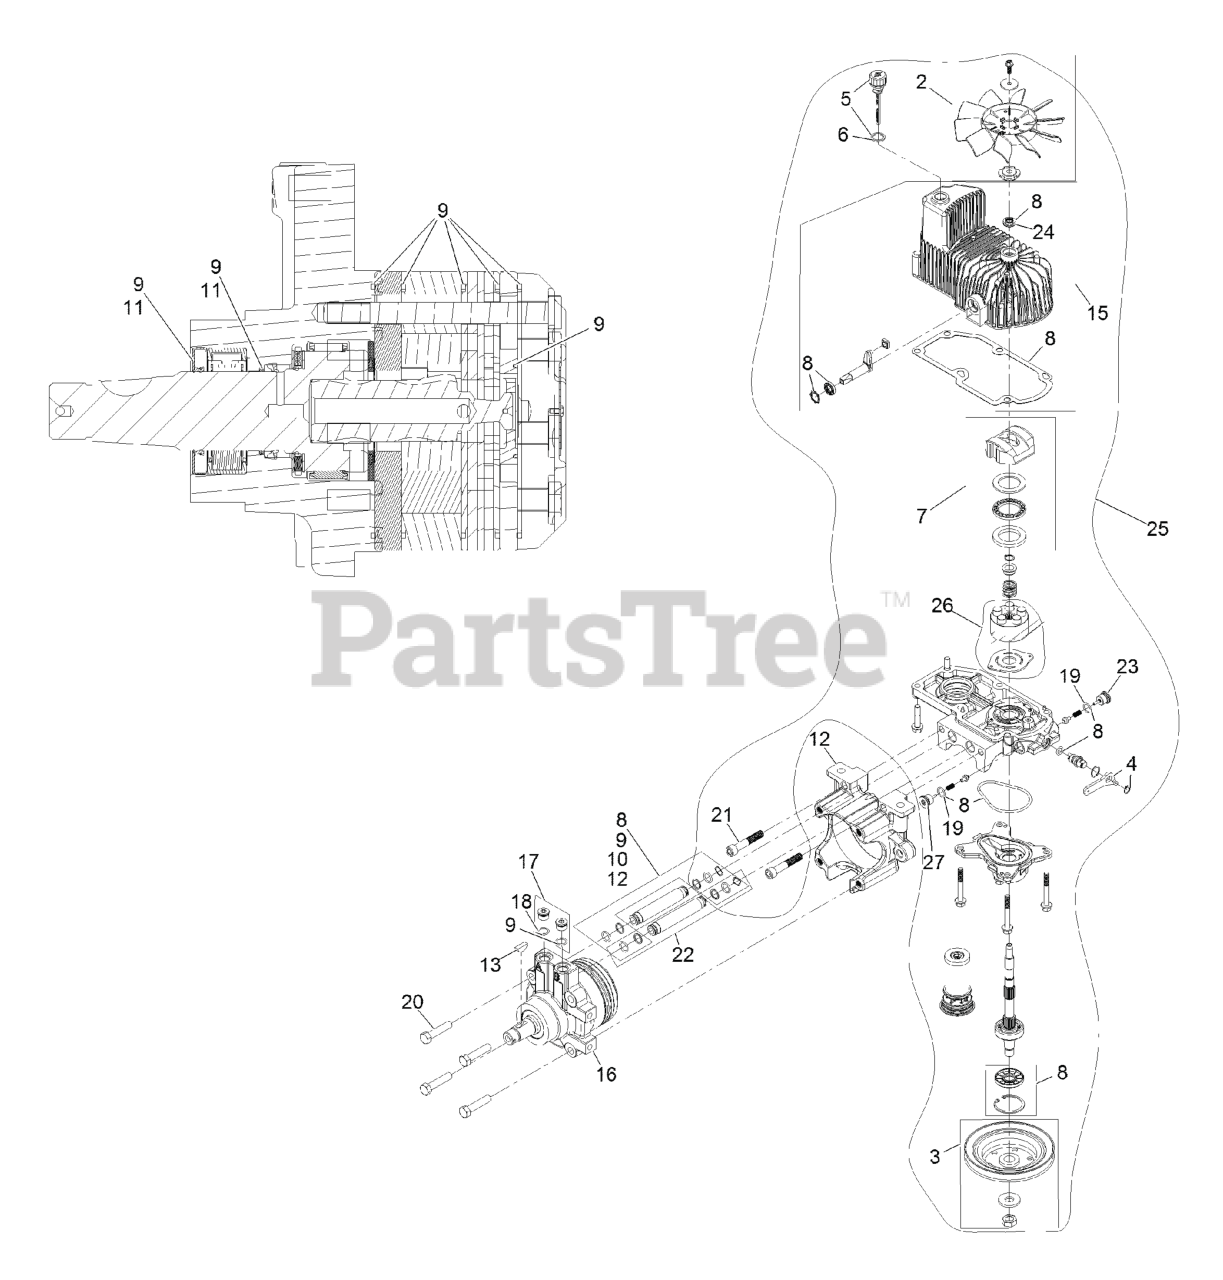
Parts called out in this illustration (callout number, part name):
2	Kit, 7.8 In Fan
3	PULLEY KIT
4	HANDLE-BYPASS VALVE, HYDRO
5	DIPSTICK-HYDRO W/GASKET
6	GASKET-DIPSTICK, HYDRO
7	SWASH BLOCK KIT
8	Kit, Pump Seal
9	MOTOR SEAL KIT
10	TUBE SEAL KIT
11	OUTPUT SHAFT SEAL KIT
12	NOSE CUP-UHT
13	KEY-WOODRUFF
15	Kit, Housing-Hydro LH
16	MOTOR-HYDRAULIC LH 240CC
17	MAGNETIC PLUGS SERVICE KIT
19	O-RING-CHECK VALVE
20	SCREW HH
21	SCREW-HSH
22	HYDRAULIC TUBE KIT
23	SHOCK VALVE, 12CC HYDRO
24	SEAL-FAN DRIVE
25	Kit, Pump Section 12Cc LH
26	Kit - 12Cc Port Plate,Rotate Grp
27	Shock Valve Orificed 3800
